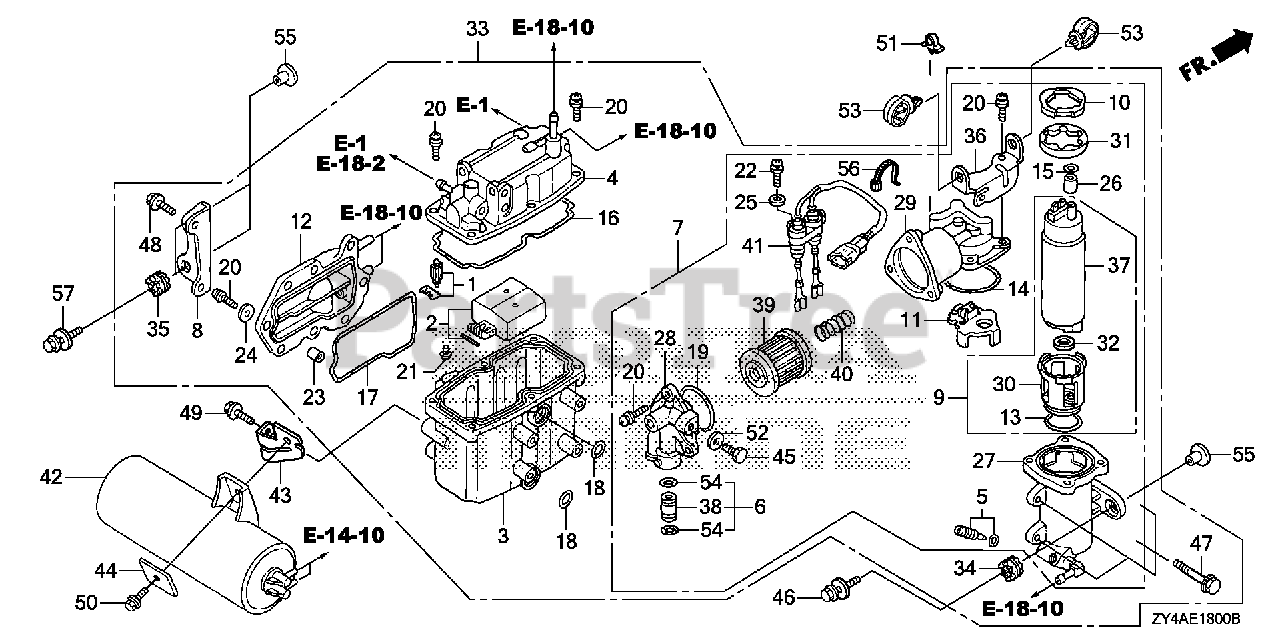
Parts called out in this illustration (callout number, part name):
1	VALVE SET, FLOAT
3	BODY
5	SCREW SET, DRAIN
7	PUMP UNIT SET A, FUEL (MSDS)
8	STAY, PLATE
9	PUMP UNIT SET B, FUEL (MSDS)
12	COVER, WATER JACKET
15	O-RING
15	O-RING (7.3X2.2) (NOK)
20	SCREW-WASHER
21	SCREW, PAN
22	SCREW, WASHER
23	COLLAR, SET
24	WASHER, PLAIN
25	WASHER, PLAIN
27	CASE, PUMP
28	COVER, PUMP
29	COVER, PUMP (A)
33	SEPARATOR ASSY., VAPOR
34	GROMMET, VAPOR SEPARATOR
35	GROMMET, VAPOR SEPARATOR
36	STAY, PLATE
37	PUMP UNIT, FUEL (MSDS)
38	JOINT, FUEL PIPE
39	SCREEN, FUEL STRAINER
40	SPRING, SET
42	TANK, VACUUM
43	STAY, VACUUM TANK
45	BOLT, SEALING (6MM)
46	BOLT-WASHER (8X35)
47	BOLT, FLANGE (6X25)
48	BOLT, FLANGE (6X16)
49	BOLT, FLANGE (6X14)
50	BOLT, FLANGE (6X12)
52	WASHER, SEALING (6MM)
53	CLIP, HARNESS
54	O-RING (7.8X1.9) (ARAI)
55	COLLAR (8.5X14.5)
57	BOLT, FLANGE (8X35)
